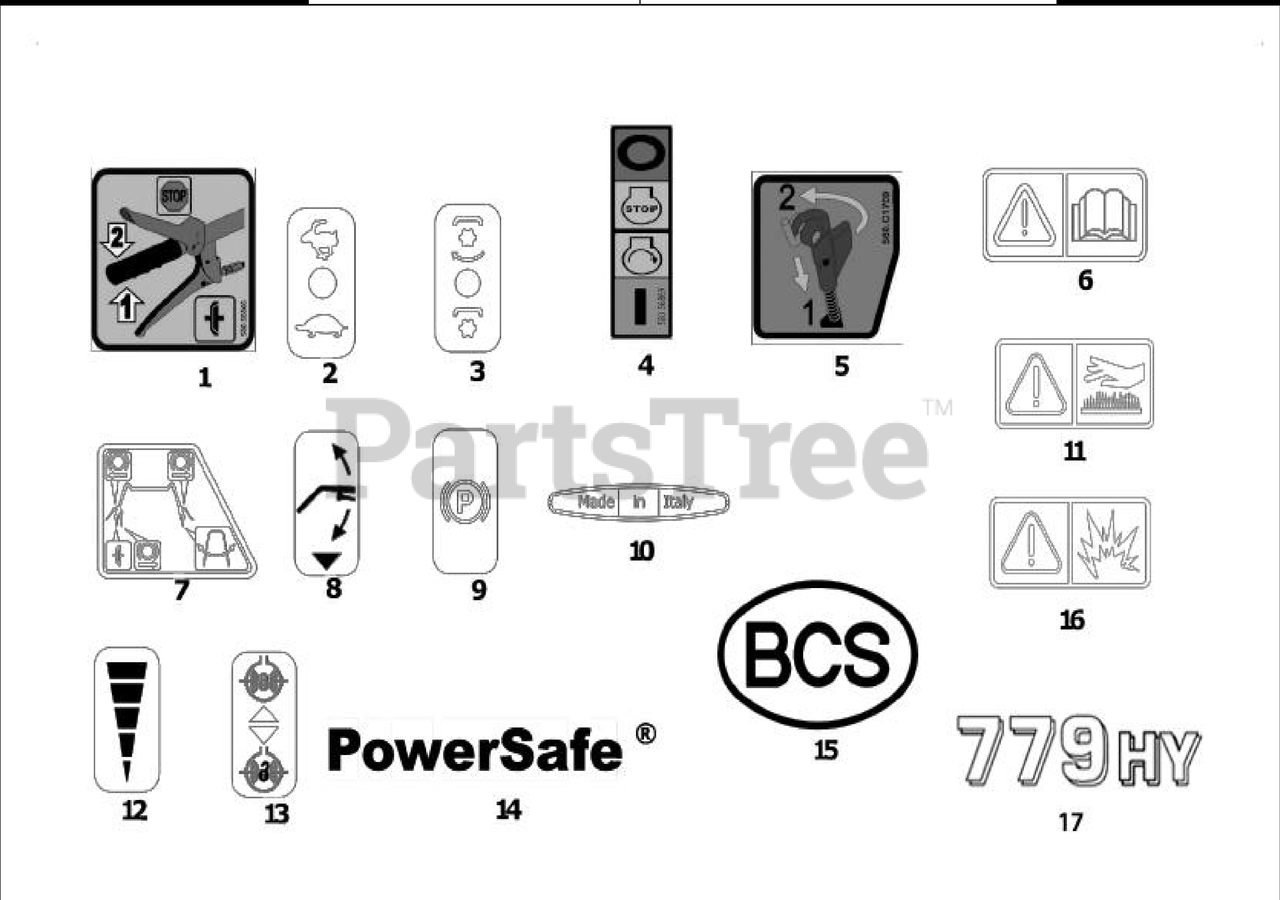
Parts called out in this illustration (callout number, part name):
1	DECAL, CLUTCH & OPC SEQUENCE
2	DECAL, HI / LO RANGE
3	DECAL, PTO ENGAGEMENT
4	DECAL, ENGINE STOP
5	DECAL, PTO SWIVEL SEQUENCE
6	DECAL, READ OWNERS MANUAL
7	DECAL, HANDLEBAR ROTATION
8	DECAL, HANDLEBAR HEIGHT
9	DECAL, PARKING BRAKE
10	DECAL, MADE IN ITALY
11	DECAL, CAUTION HOT
12	DECAL, THROTTLE
13	DECAL, DIFFERENTIAL LOCK
14	DECAL, POWERSAFE BRAND
15	DECAL, OVAL LOGO
16	DECAL, FUEL SPARK DANGER
17	DECAL, 779 HY
